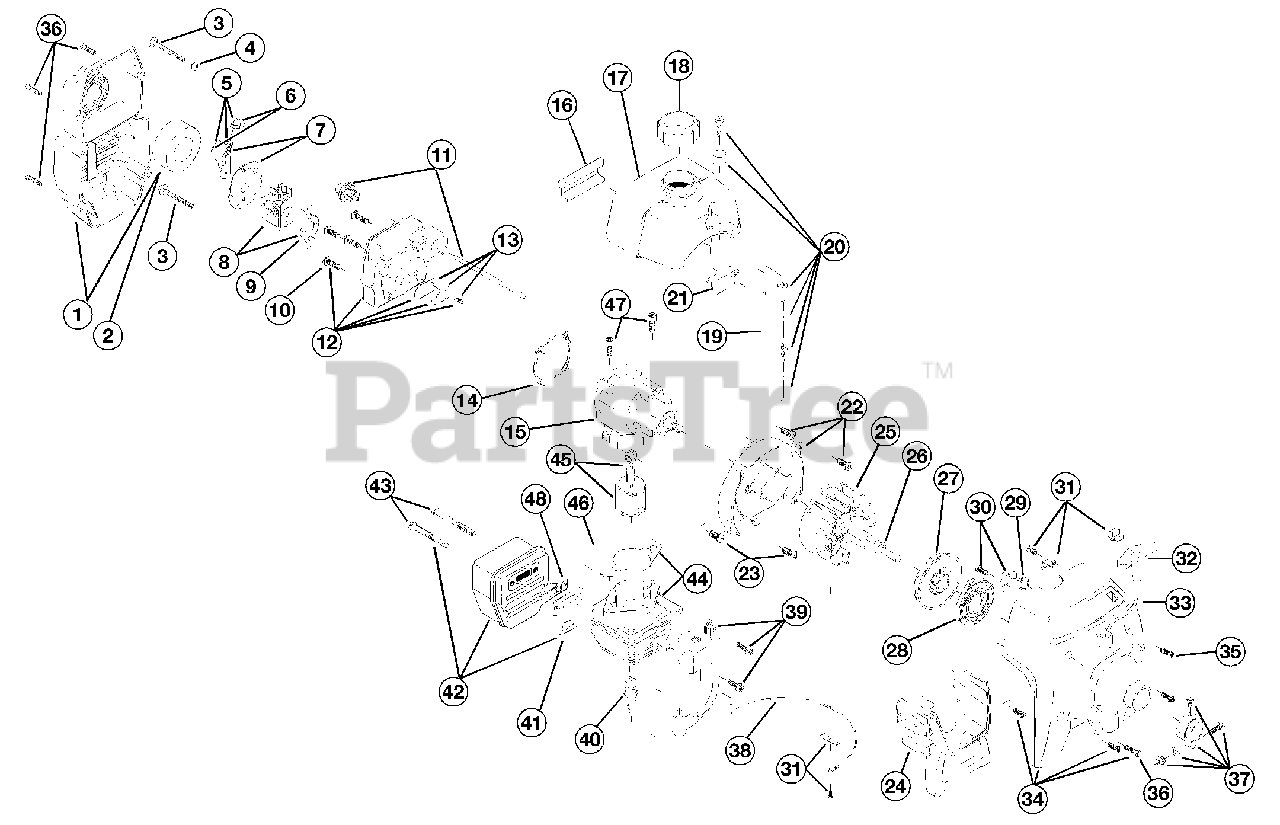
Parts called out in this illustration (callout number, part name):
1	Air Cleaner/Muffler Cover Assembly
2	Air Cleaner Filter
3	Carburetor Mounting Screw Assembly
4	Wavey Washer
5	Choke Lever Assembly
6	Choke Knob and Screw
7	Choke Lever and Plate
8	Carburetor Assembly
9	Carburetor Gasket
10	Carb Mount Screw
11	Primer and Hose Assembly
12	Carb Mount Assembly
13	Reed Assembly
14	Carburetor Mount Gasket
15	Crank Case Service Assembly
16	Rear Mounting Pad
17	Fuel Tank Assembly
18	Fuel Cap Assembly
19	Fuel Return Line
20	Fuel Line Assembly
21	Front Mounting Pad
22	Shroud Assembly
23	Shroud Screw
24	Shroud Extension and Stand
25	Flywheel Assembly
26	Square Nut Drive
27	Recoil Pulley Assembly
28	Recoil Spring
29	Rope Guide
30	Pulley Retainer Assembly
31	Switch Assembly
32	Pull Handle
34	Starter Housing Assembly
35	Housing Screw
36	Cover Screw
37	Upper Clamp Assembly
38	Wire Lead
39	Module Assembly
40	Spark Plug
41	Exhaust Gasket
42	Muffler Assembly
43	Muffler Mounting Bolt Assembly
44	Cylinder Assembly
45	Piston and Rod Assembly
46	Cylinder Gasket
47	Cylinder Bolt
48	Spark Arrestor Screen
